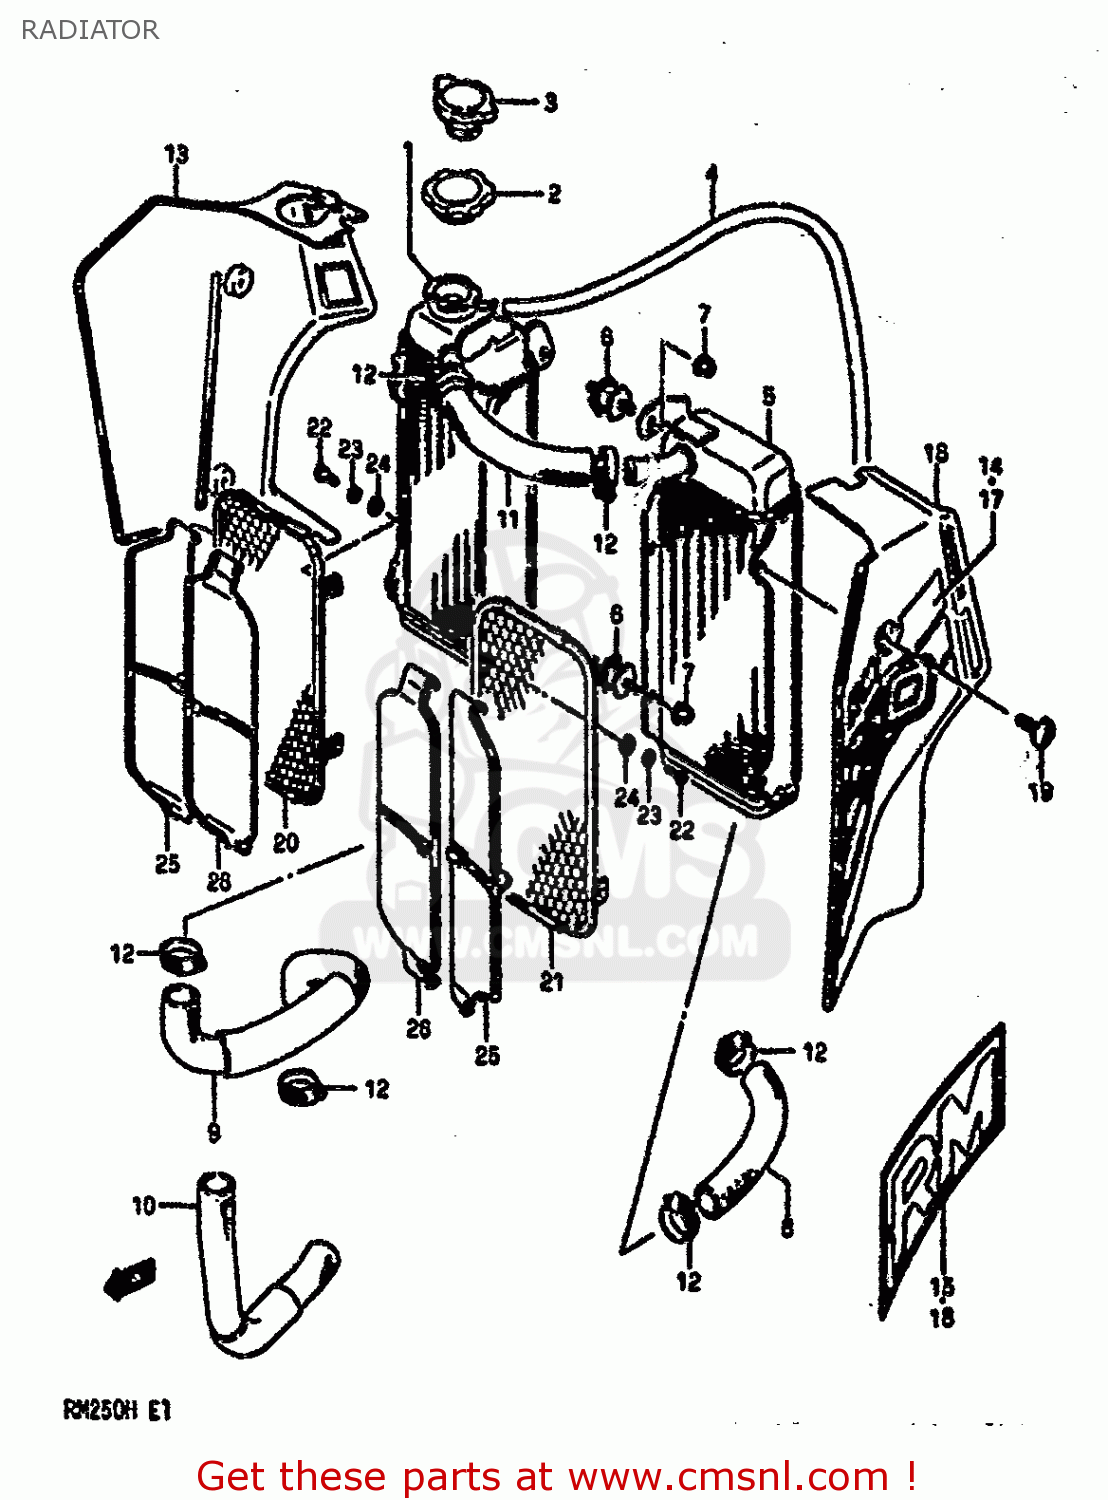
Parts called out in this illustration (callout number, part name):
1	RADIATOR COMP,WATER,RIGHT
2	CAP,RADIATOR 1.1
3	CAP,RADIATOR 1.1
4	HOSE
5	RADIATOR COMP,WATER,LEFT
6	BOLT,RADIATOR CUSHION
7	NUT 6MM
8	HOSE,RADIATOR INLET
9	HOSE,RADIATOR OUTLET
10	HOSE,RADIATOR OUTLET
11	HOSE,RADIATOR JOINT
12	CLAMP
13	COVER,RADIATOR
14	TAPE SET,RADIATOR COVER
15	TAPE SET,RADIATOR COVER STRIPE
16	COVER,RADIATOR
17	TAPE SET,RADIATOR COVER
18	TAPE SET,RADIATOR COVER STRIPE
19	SCREW(6X14)
20	BUMPER,RADIATOR,RIGHT
21	BUMPER,RADIATOR,LEFT
22	SCREW
23	WASHER,LOCK
24	WASHER
25	LOUVER,RADIATOR NO.1
26	LOUVER,RADIATOR NO.2
